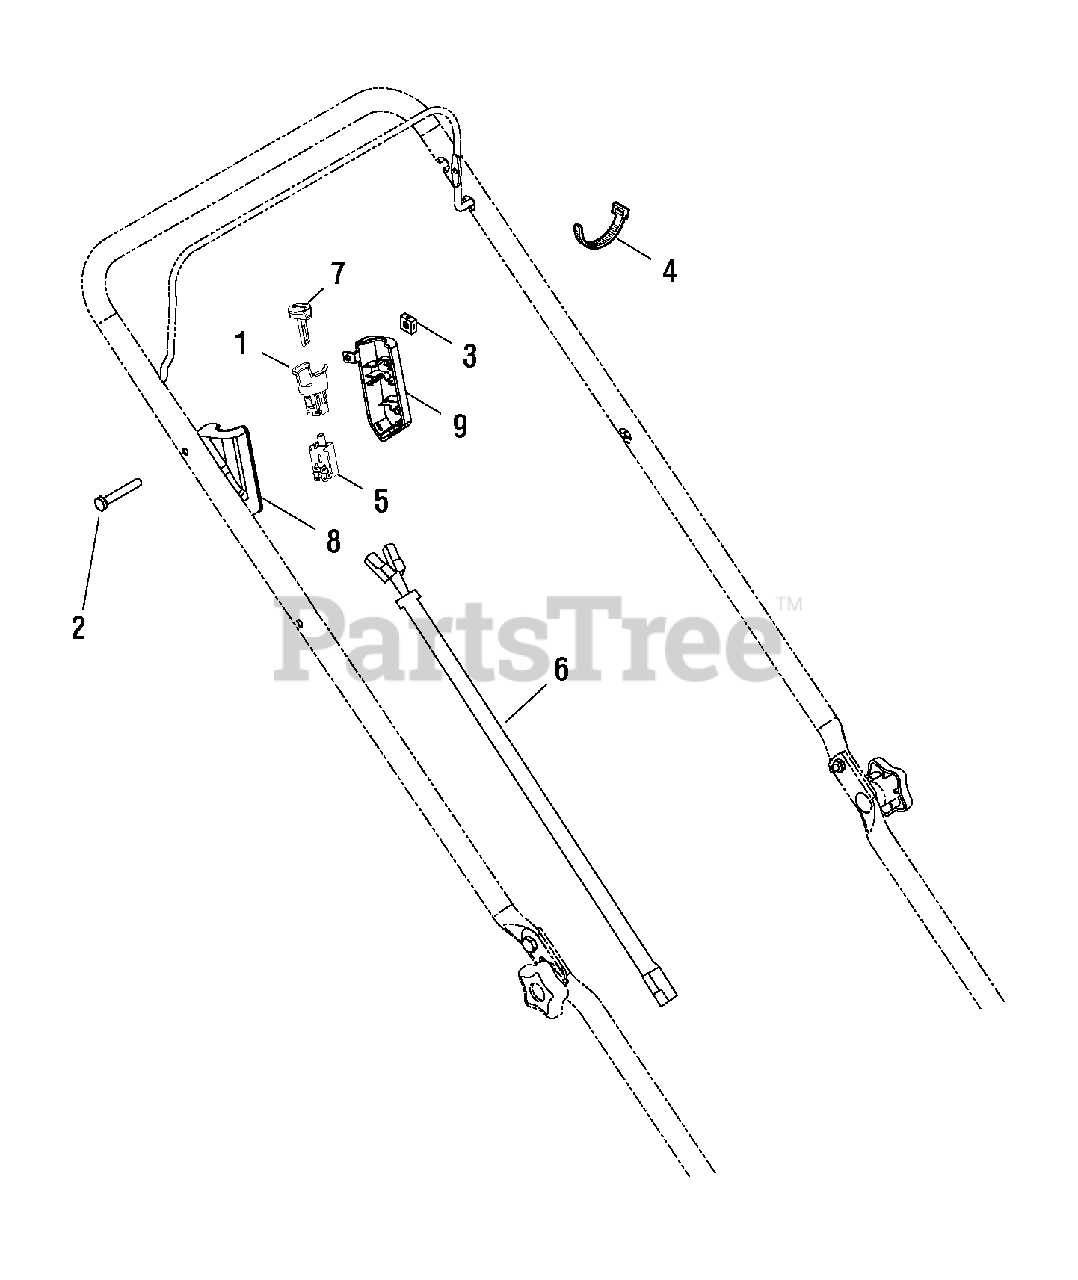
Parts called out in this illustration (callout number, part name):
2	SCREW, 1/4-20 x 1.65 Torx Hd.
3	NUT, Square, 1/4-20
4	CABLE TIE
5	SWITCH, Plunger
6	HARNESS
8	HOUSING, Electric Start, RH
9	HOUSING, Electric Start, LH
